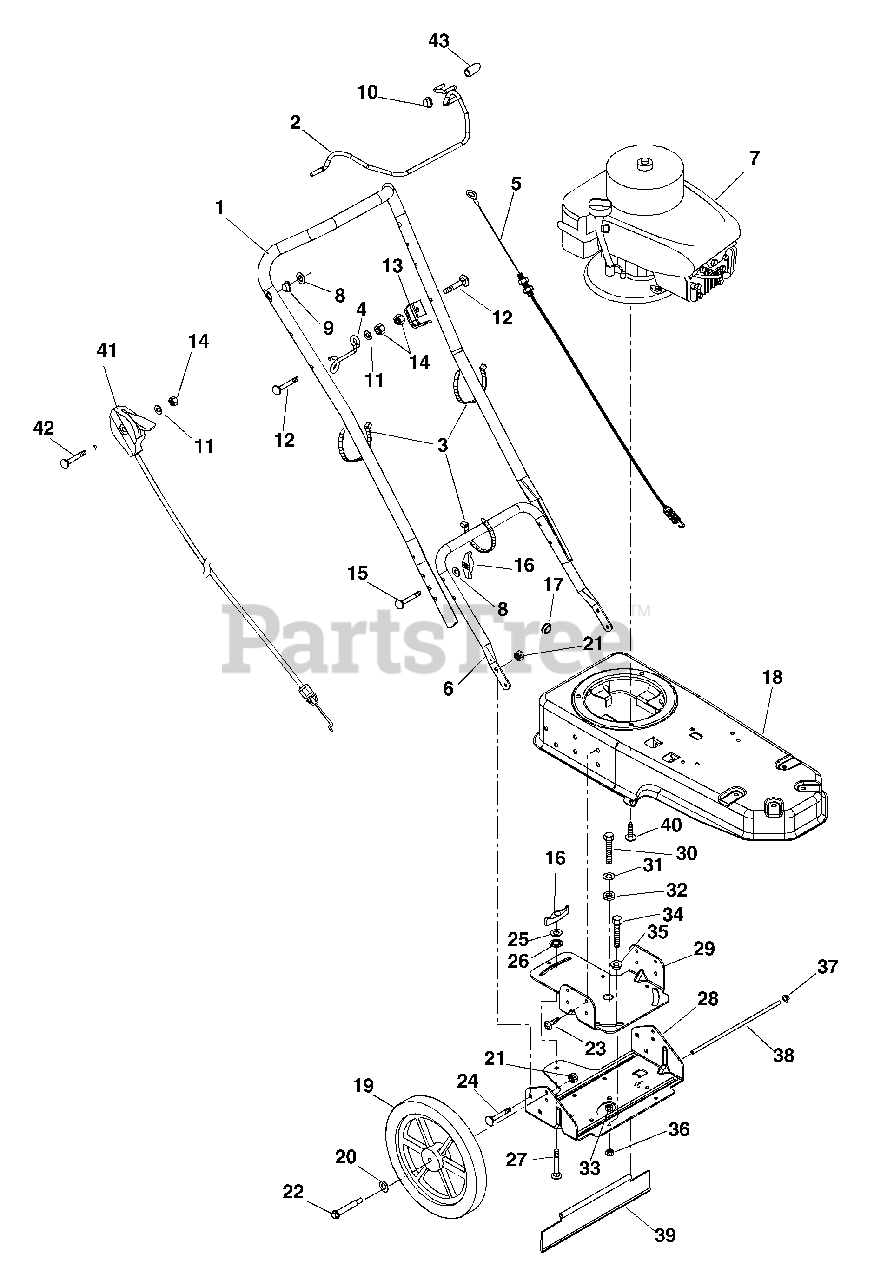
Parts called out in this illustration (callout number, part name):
1	HANDLEBAR - UPPER
2	BAIL SS LF
3	CABLE TIE LG 5-1/2
4	GUIDE - PULLCORD
5	CABLE - CONTROL
6	HANDLEBAR - LOWER
7	ENGINE - 6 HP TEC CENTURA
8	@WSHR-FL-STL.344X.688X.065YWZC
9	BSHG-FLG .325X.444X.440X.560
10	PUSH NUT, .25
11	@WSHR-FL-STL.281X.62X.065 YWZC
12	BLT-RDHDXLSQNK.25-20X1.25 G5ZC
13	ANCHOR - CABLE
14	@NUT-LK-CTR .25-20 YWZC
15	BLT-RDHDSQNKFT .31-18X2.0 G5YZ
16	KNOB - WING .312-18 UNC
17	GROMMET .50 ID
18	FRAME - TRIMMER
19	WHEEL 14 X 1.75 X .50
20	WSHR-FL-STL .52X.827X.062 YWZC
21	@NUT-LK-CTR .38-16 YWZC
22	BLT-SHLDR .38-16X2.50 HWH G5
23	@SCR-TAP .38-16X.75 HWH TR YWZ
24	@BLT-RDHDSQNK .38-16X.75 G5YZ
25	@WSHR-FL-STL.38X.875X.083 YWZC
26	NUT-PUSH .312
27	@BLT-RDHDSQNK .31-18X1.00 G5YZ
28	BRACKET - AXLE - SWIVEL
29	BASE - SWIVEL
30	@BLT-HEX .50-13X1.00 GR5 YWZC
31	@WSHR-FL-STL.563X1.38X.109YWZC
32	SPACER .531 X 1.00 X .225
33	@NUT-LK-CTR .50-13 YWZC
34	@BLT-HEX .31-18X1.00 GR5 YWZC
35	BSHG-FLG .32X.500X.344X.880
36	@NUT-LK-CTR .31-18 YWZC
37	NUT-PUSH .312 DIA. PAL
39	GUARD - REAR - SWIVEL
40	@SCR-TAP .38-16X1.00 HWH TR YZ
41	CONTROL - THROTTLE
42	BLT-RDHDXLSQNK .25-20X2.0 G5YZ
43	CAP, VINYL, .25 ID
